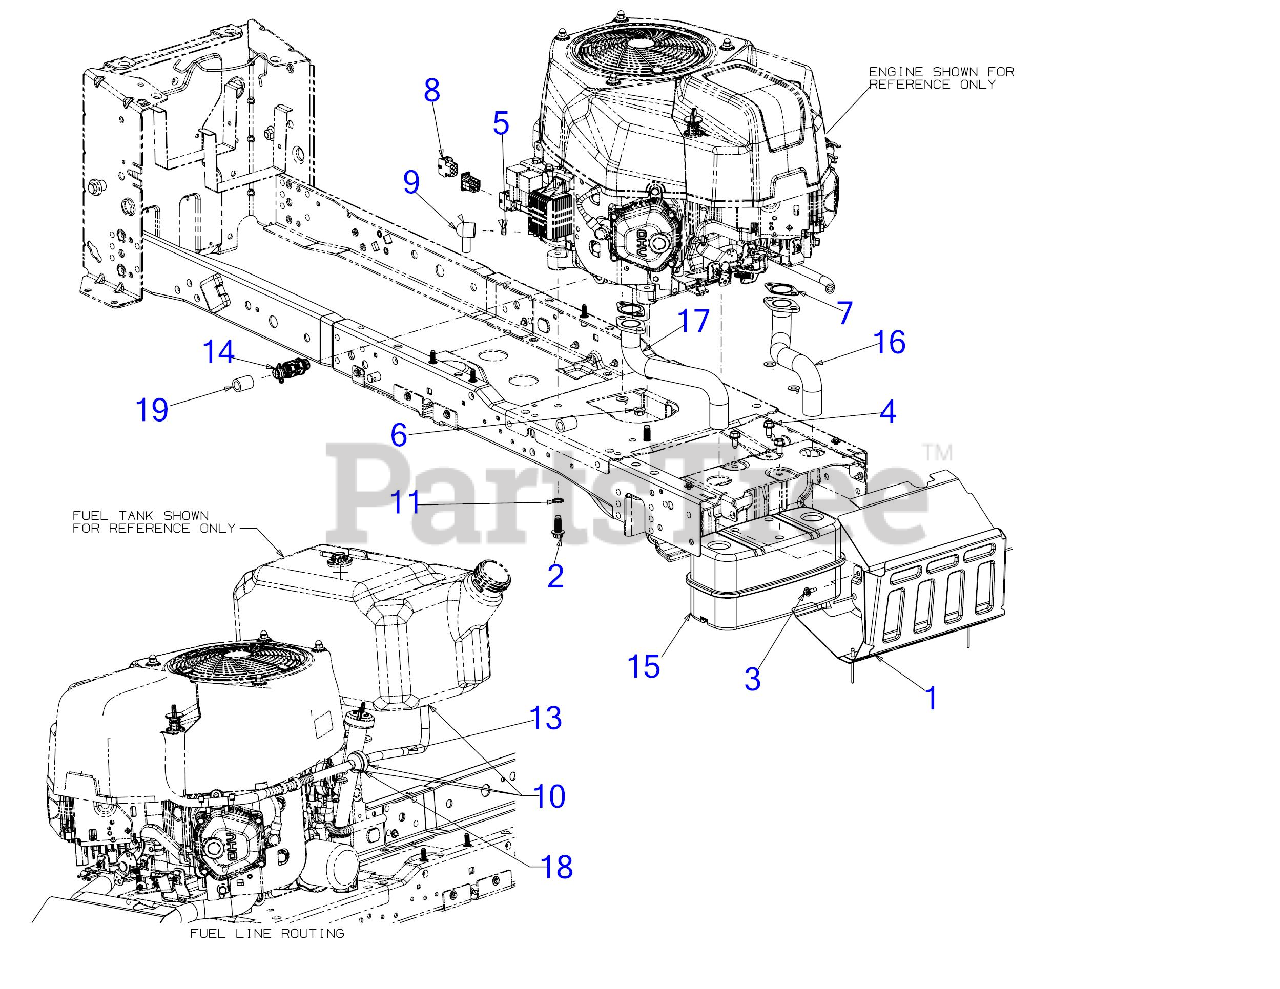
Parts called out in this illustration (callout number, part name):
1	MUFFLER SHIELD ASSEMBLY
1	RIVET - 3/16"
2	SCREW 3/8-16 x 1
3	SCREW M6-1 x .625
4	SCREW M8-1.25 x .750
5	HEX NUT
6	HEX FLANGE NUT M8X
7	EXHAUST GASKET
8	JUMPER HARNESS
9	TERMINAL COVER (RED)
10	HOSE CLAMP 1/20
11	LOCK WASHER 3/8
13	FUEL HOSE LOW PERMEATION
14	OIL DRAIN VALVE
15	EXHAUST MUFFLER (TWIN)
16	EXHAUST PIPE (LH)
17	EXHAUST PIPE (RH)
18	FUEL FILTER
19	DRAIN HOSE 14''
